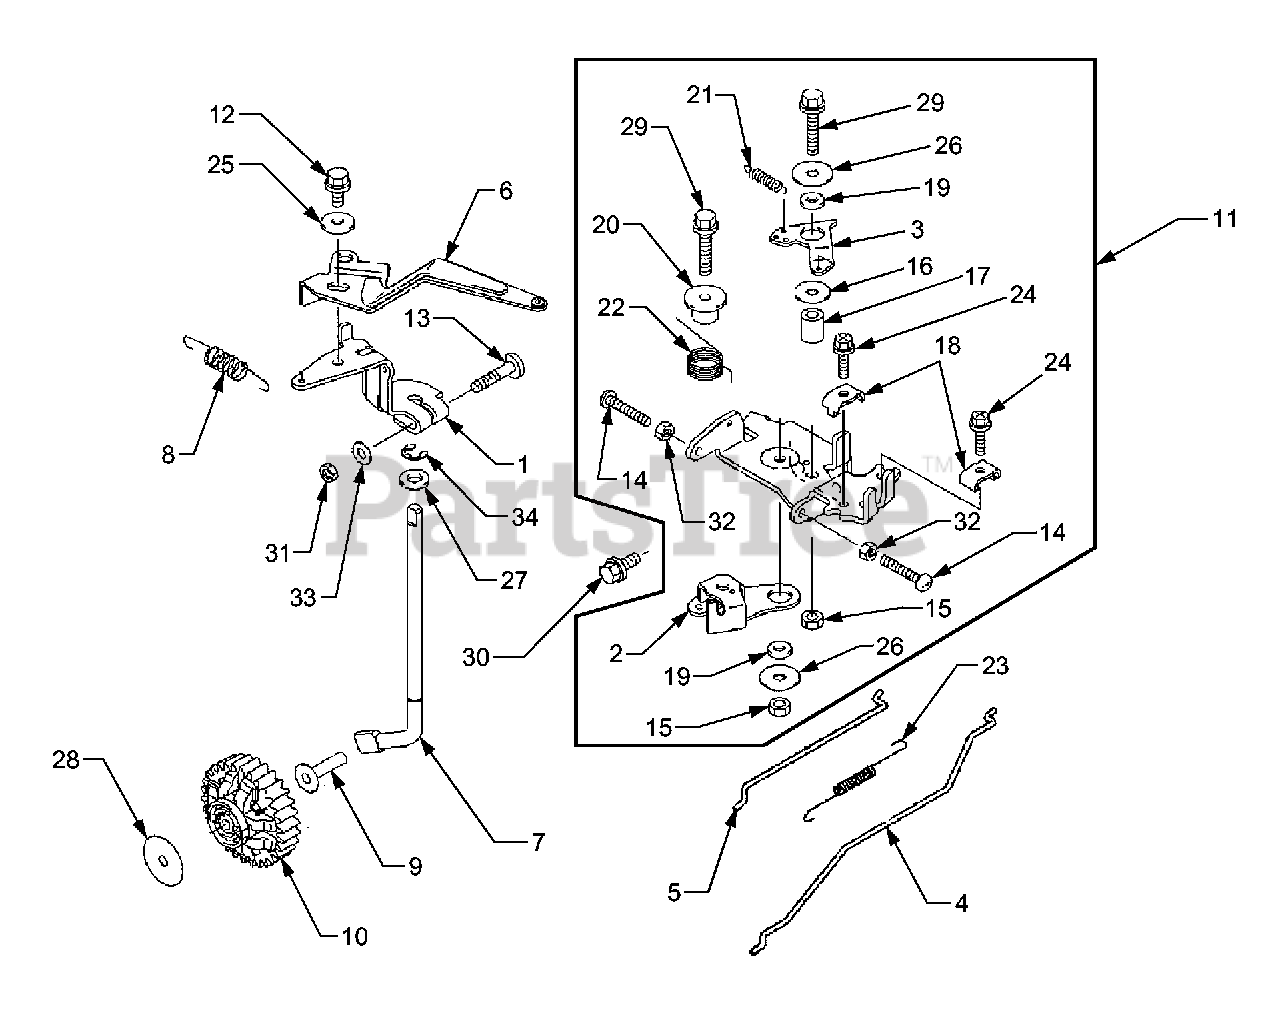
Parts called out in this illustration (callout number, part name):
2	Lever, Throttle
6	Arm Assembly
7	Arm, Governor Pivot
8	Spring, Governor
10	Gear Assembly, Governor
11	Panel, Control Complete
12	Bolt
14	Screw, 5 x 30
16	Washer, 6 x 19 x 1.2
19	Collar, 6 x 13 x 2.3
26	Washer, 6.5 x 22 x 1.2
27	Washer, 8.3 x 16 x 2.3
28	Washer, 6.2 x 30 x 0.5
29	Bolt, Flanged
30	Bolt, Flanged
31	Nut, Hex
33	Washer, Plain
34	Circlip, E-Ring
